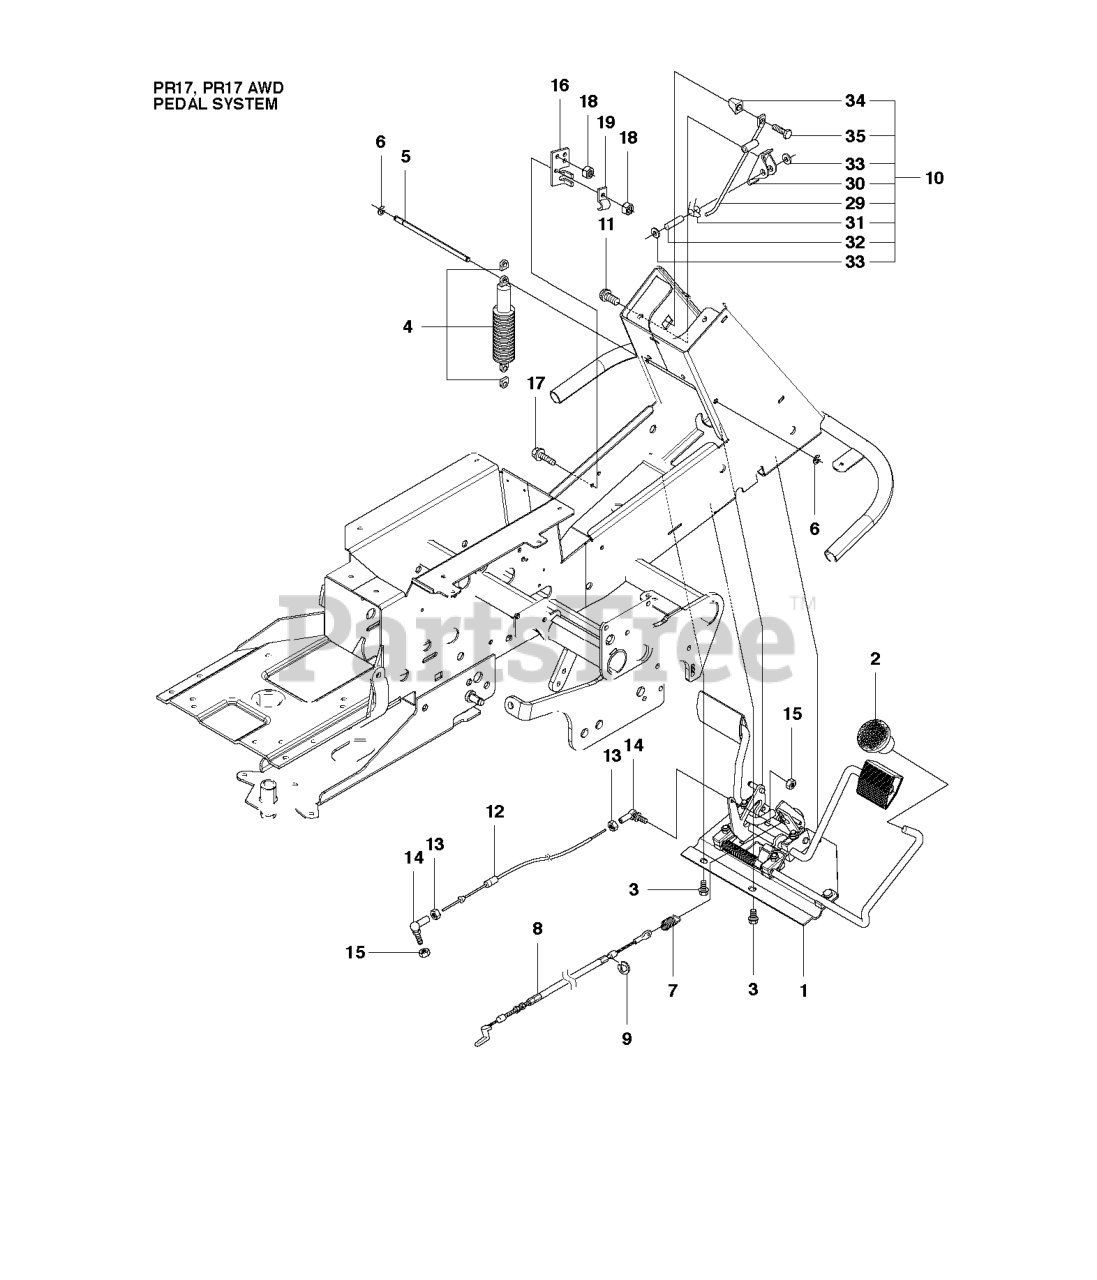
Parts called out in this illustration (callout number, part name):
1	PEDAL ASSEMBLY
2	KNOB
4	SHOCK ABSORBER
8	BRAKE WIRE
12	CONTROL CABLE
14	CONNECTOR
15	LOCKNUT M5
18	LOCKNUT M5
